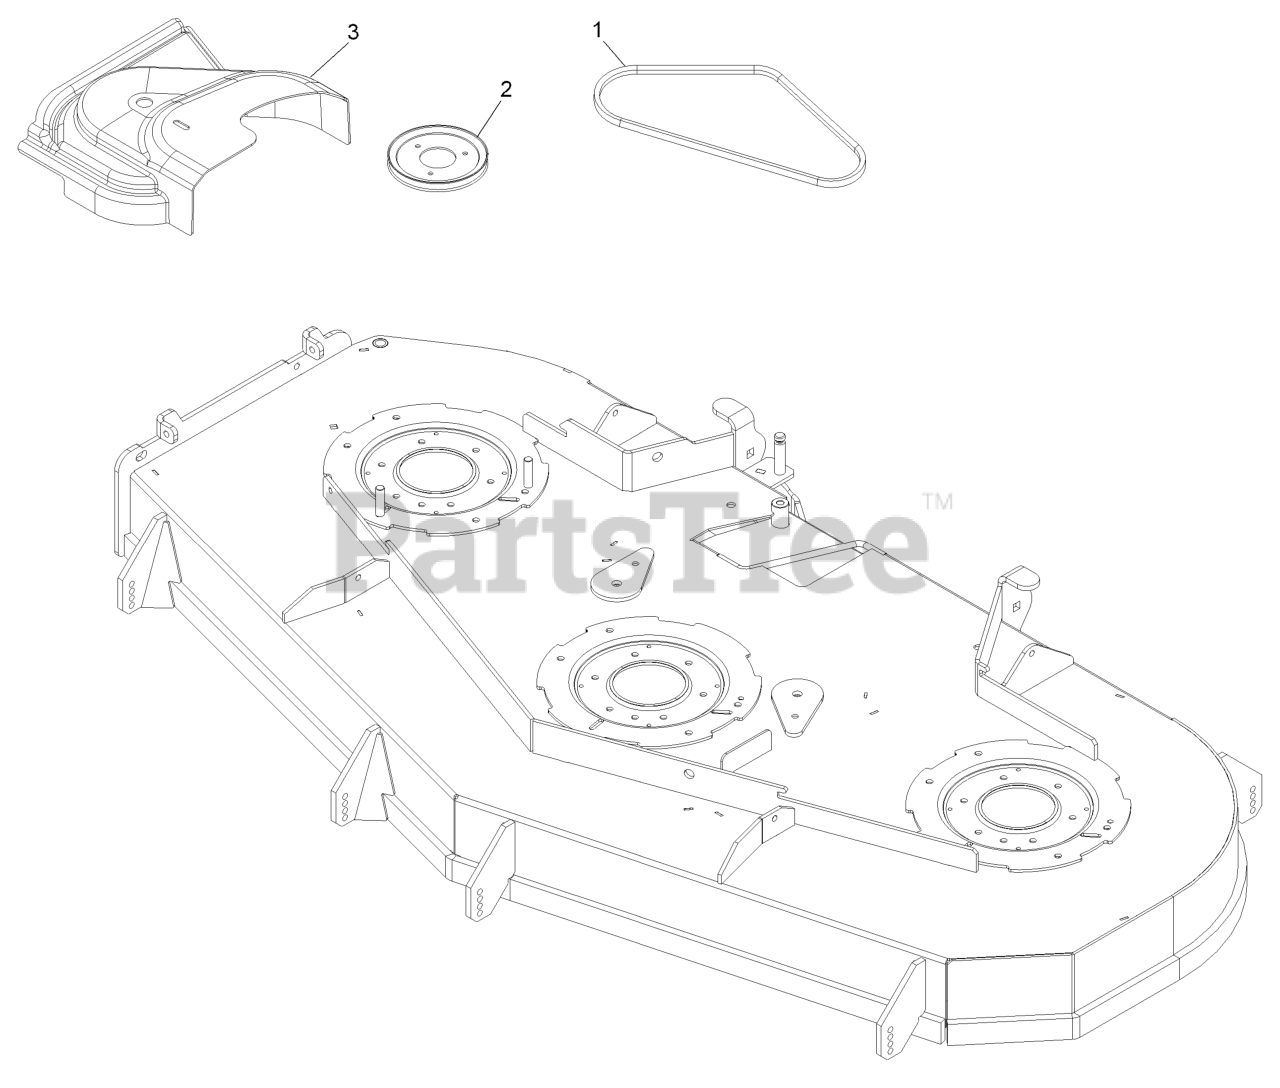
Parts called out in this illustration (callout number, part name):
1	BELT, BLOWER DRIVE 72
2	SHEAVE,DRIVE LZUV 726
3	COVER,BELT UV 72
